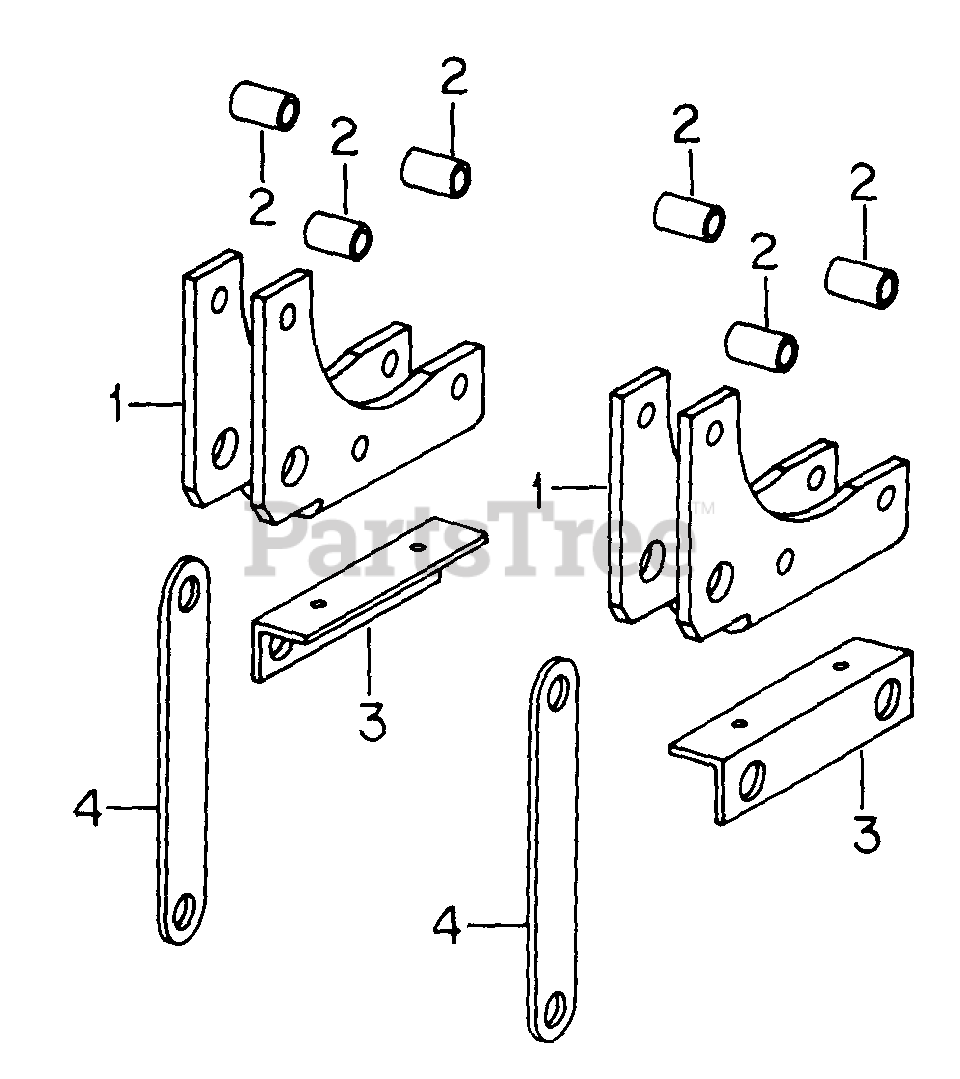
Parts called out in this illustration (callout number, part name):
1	SUPPORT, LOWER LINK
2	SPACER, LOWER LINK SUPPORT
3	ANGLE, REAR HANGER
4	LINK, LIFT
